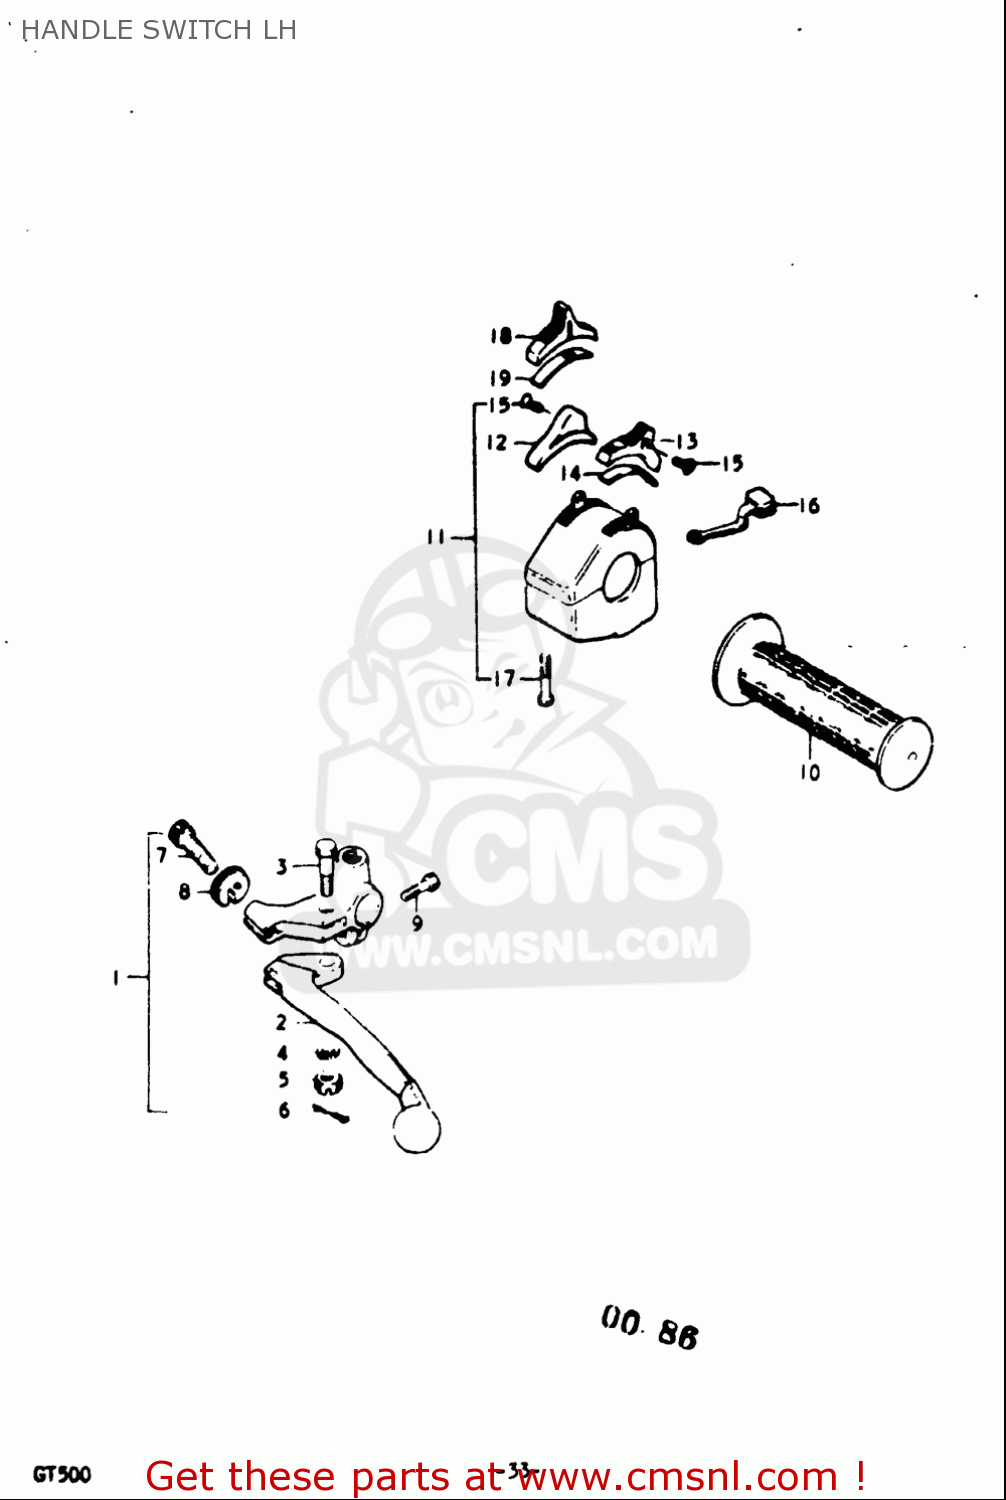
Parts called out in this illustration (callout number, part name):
1	LEVER ASSY,CLUTCH
2	LEVER,CLUTCH
3	BOLT,LEVER PIVOT
4	WASHER,LOCK
5	NUT,LEVER FITTNG
6	PIN 16X20
7	ADJUSTER,CABLE
8	NUT,CABLE ADJUSTER
9	BOLT
10	GRIP
13	KNOB
14	PLATE,SWITCH KNOB
15	SCREW
17	SCREW
18	KNOB,HANDLE SWITCH
19	PLATE,SWITCH KNOB
